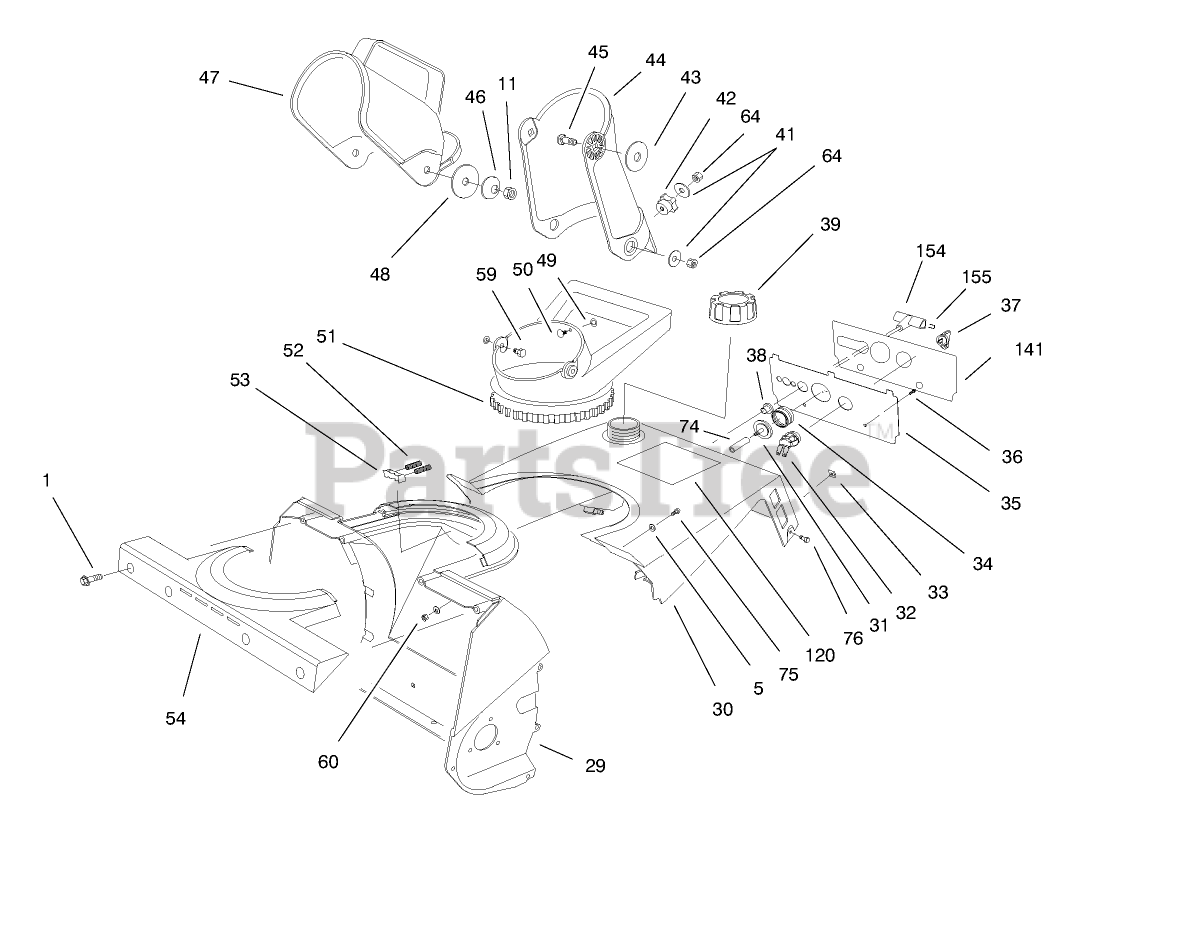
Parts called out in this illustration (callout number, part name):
1	SCREW-PLASTIC
5	WASHER-FLAT
11	NUT-LOCK, NI
29	HOUSING
31	BODY-PRIMER
32	SWITCH
34	BULB-PRIMER
36	SCREW-SHWH, THREAD FORMING
37	KEY-IGNITION
38	GUIDE-ROPE, STARTER
41	WASHER-FLAT
42	KNOB-CHUTE
43	WASHER-RUBBER
45	BOLT-CARR
46	WASHER-BELLEVILLE
47	DEFLECTOR-CHUTE
48	WASHER-FLAT
49	PUSHNUT-RETAINER, BOLT
50	SCREW-CARR
51	HANDLE-CHUTE
52	SPRING-COMPRESSION
53	DETENT-CHUTE
54	RETAINER-CHUTE
59	SCREW-HH
60	NUT-LOCK, NI
64	NUT-LOCK, NI
74	HOSE-PRIMER
75	SCREW-PPH
76	SCREW-THREAD FORMING
120	DECAL - POWERLITE EL.
154	HANDLE-STARTER
155	STAPLE-HANDLE
